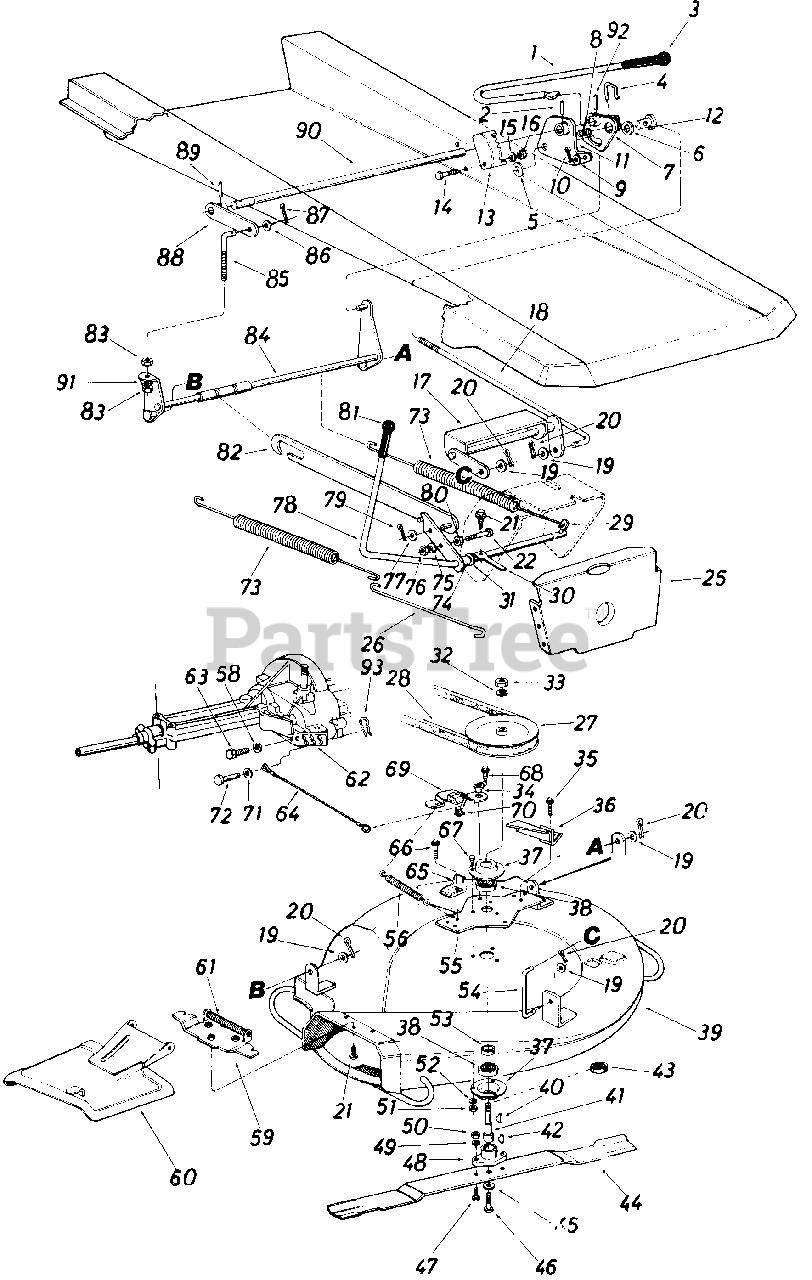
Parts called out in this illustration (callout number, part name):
1	Deck Lift Handle
2	Spring Pin Spir. 1/4" Dia. x 1.50" Lg.
3	G ri p
4	Cotter Pin
5	Fl-Wash. 518" I.D. x 1.0" O.D. x .12
6	Fl-Wash. 518" I.D. x 1.25" O.D. x .60
7	Deck Lift Handle Brkt. Ass'y.
8	Compression Spring .50" O.D. x 1.04
9	Fl-Wash 385" I.D. x .87" O.D. x .06
10	Cotter Pin 118" Dia. x 1.00"
11	Deck Lift Brkt. Ass'y.-L.H.
12	Adj. Ferrule-Deck Lift Handle
13	Index Bracket
14	Hex Bolt 5/16-18 x .75" Lg.
15	L-Wash. 5/16" I.D.
16	Hex Nut 5/16-18 Thd.
17	Deck Lift Ass'y. Front
18	Deck Lift Connecting Rod
19	Fl-Wash. .385" I.D. x .87" O.D. x .06
20	Cotter Pin 1/8" Dia. x 1.00"
21	Hex Wash. Hd. Self-Tap Scr. 1/4-20 x .50" Lg.
22	Hex Bolt 5/16-18 x 1.5" Lg.
25	Pivot Bar Bracket
26	Spring Hook
27	Deck Pulley 6.0" O.D.
28	"V"-Belt 1/2" x 52" Lg.
29	Spec. Clevis Pin .250" Dia.
30	Switch Actuator
31	Fl-Wash. .531" I.D. x .930" O.D. x .050
32	Fl-Wash. 518" I.D.
33	Hex Jam Nut 5/8-11 Thd.
34	Shoulder Spacer
35	Hex Wash. Hd. Scr. 5/16-18 x .62" Lg.
36	Belt Guard Ass'y.
37	Bearing Housing 1.85" I.D.
38	Ball Brg. .787" I.D. x 1.85" O.D. x .551
39	26" Deck Ass'y.
40	#61 Hi-Pro Key 3/16" x 5/8" Dia.
41	Blade Spindle
42	#6 Hi-Pro Key 5/32" x 518" Dia.
43	Bearing Shield
44	26" Blade
45	L-Wash. 3/8" I.D. Heavy Duty
46	Hex Bolt 3/8-24 x 1.50" Lg. (Grade 5)
47	Hex Bolt 5/16-24 x 1.00" Lg. (Grade 5)
48	Blade Adapter Kit
49	L-Wash. 5/16" I.D.*
50	Hex Nut 5/16-24 Thd.
51	Hex Nut 5/16-18 Thd.
52	L-Wash. 5/16" I.D.
53	Spacer.836" I.D. x 1.01" O.D. x .320
54	Deck Link 3.9" Lg.
55	Belt Guard Plate Ass'y.
56	Spring .38" O.D. x 3.25" Lg.
58	L-Wash. 1/4" I.D.
59	Adapter Ass'y.-Chute
60	Chute Deflector Ass'y. Comp.
61	Torsion Spring
62	Lower Inside Belt Guard
63	Hex Bolt 1/4-20 x .62" Lg.
64	Brake Cable Ass'y.
65	Belt Keeper Ass'y.
66	Hex Wash. Hd. Scr. 5/16-18 x .62" Lg.
67	Hex Sems Bclt 5/16-18 x 1.00" Lg.
68	Hex Wash. Hd. 3/8" x .75" Lg.
69	Blade Brake Brkt. Ass'y.
70	Cap Speed Nut 1/4" Rod
71	Fl-Wash. 1/4" I.D. x .50" O.D.
72	Clevis Pin 1/4" x 1/2"
73	Extension Spring .99" O.D. x 14.2" Lg.
74	Sleeve .511" I.D. x .70" x .37" Lg.
75	L-Wash. 5/16" I.D.
76	Hex Nut 5/16-18 Thd.
77	Fl-Wash. .385" I.D. x .87" O.D. x .06
78	Blade Engagement Lever Ass'y.
79	Cotter Pin 1/8" Dia. x 1.00" Lg.*
80	Hex Nut 5/16-18 Thd.*
82	Deck Drive Control Brkt. Ass'y.
83	Hex Nut 3/8-16 Thd.
84	Deck Link Ass'y.-Rear
85	Deck Adj. Scr. 3/8-16 Thd.
86	Fl-Wash. .385" I.D. x .87" O.D. x .06
87	Cotter Pin 1/8" Dia. x 1.00"
88	Deck Lift Brkt. Ass'y.-R.H.
89	Spring Pin Spir. 1/4" Dia. x 1.50" Lg.
90	Rear Height Adj. Shaft
91	L-Wash. 3/8" I.D.
92	Spring Pin Spir. 3/16" Dia. x 1.50" Lg.
93	Int. Cot. Pin 5/16" Dia.
